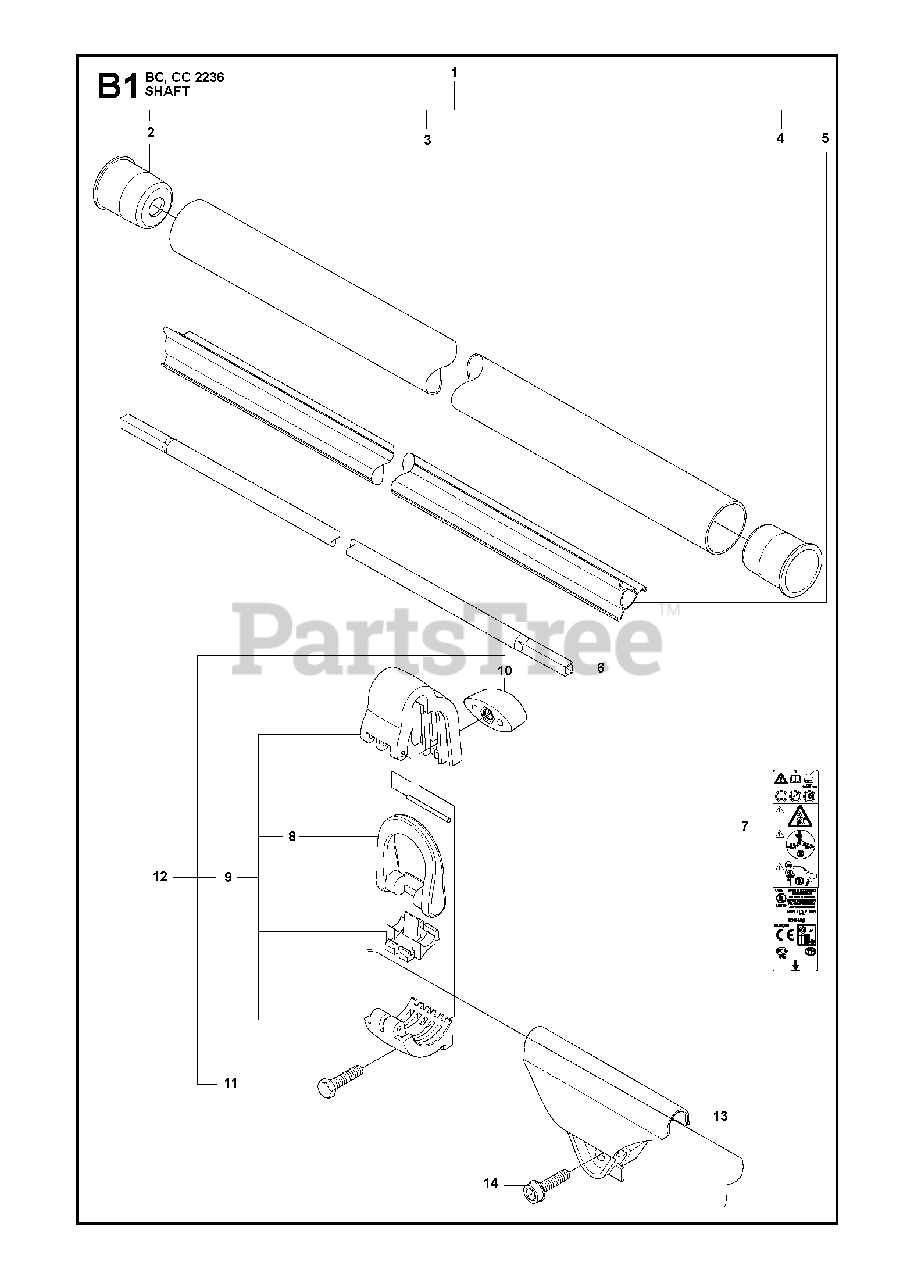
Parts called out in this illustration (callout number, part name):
1	TUBE
2	PLUG
3	RP TUBE
4	PLUG
5	GUIDE
6	SHAFT
7	RP WARNING DECAL
8	LOOP
11	SCREW M6S 5X20
